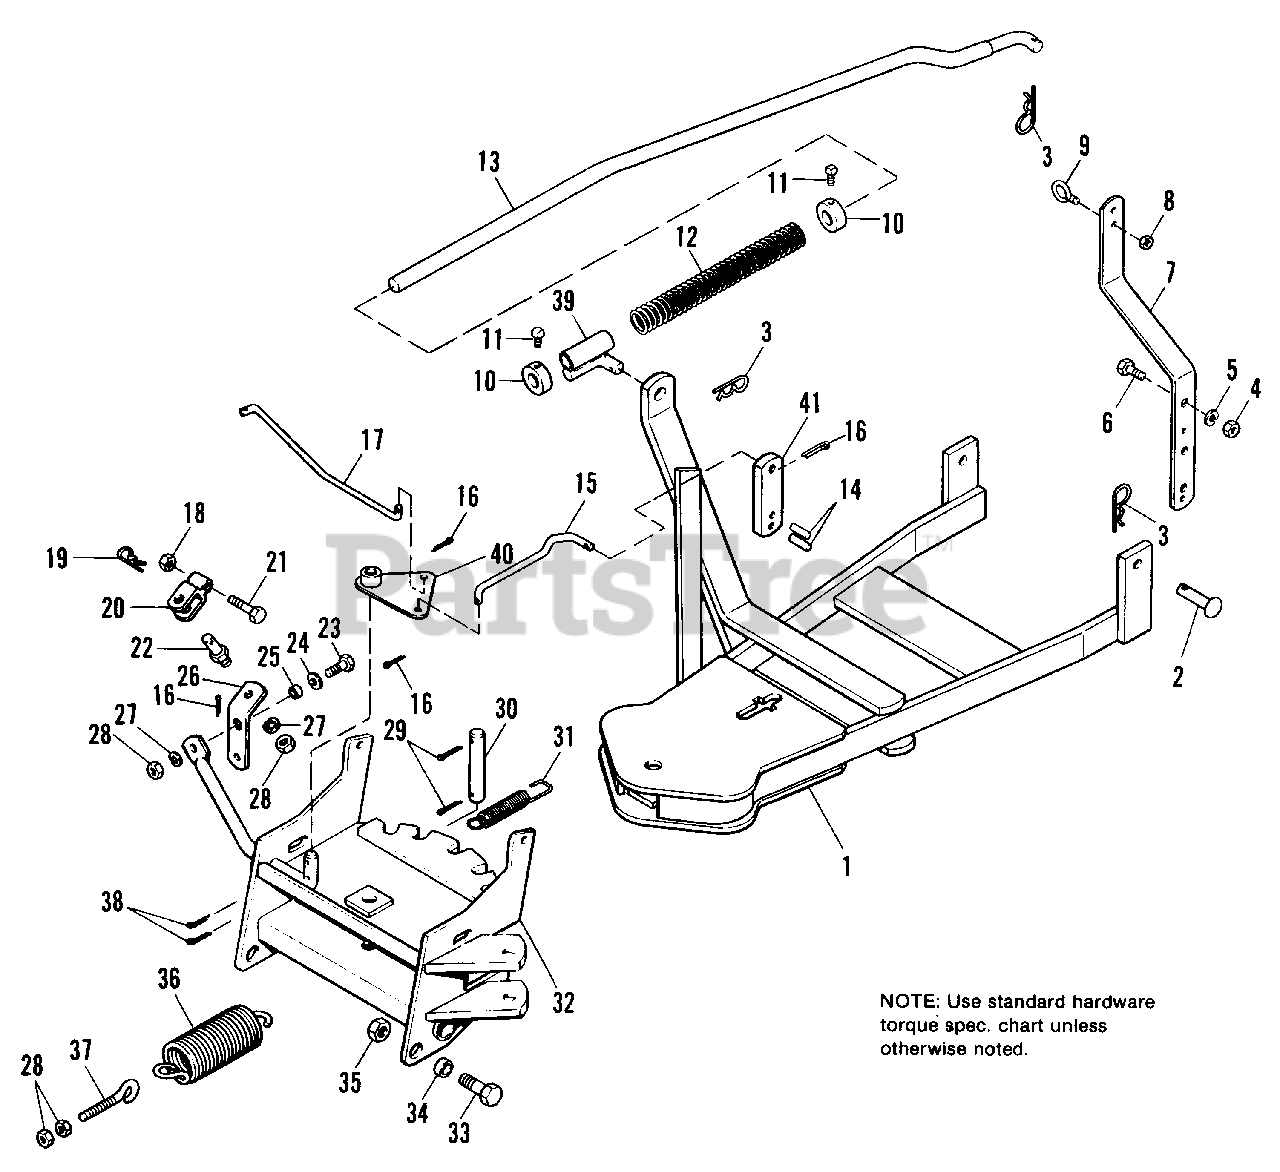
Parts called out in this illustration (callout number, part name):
1	BAR ASSY., Push
2	PIN
3	CLIP, Spring
4	NUT, Hex, Full, 3/8-16
5	LOCKWASHER, 3/8
6	CAPSCREW, Hex Hd., 3/8-16 x 7/8
7	BRACKET, Handle Support
8	LOCKNUT, Hex, 1/4-20
10	COLLAR, Set
11	SETSCREW, Sq. Hd., 5/16-18 x 1-1/2
14	PIN, Spring, 7/32 x 1
16	COTTER PIN, 3/32 x 3/4
18	LOCKNUT, Hex, 5/16-18
19	CLIP, Spring
21	CAPSCREW, Hex Hd., 5/16-18 x 1-1/2
22	STUD, Pivot
23	CAPSCREW, Hex Hd., 5/16-18 x 1
24	WASHER, Plain, 5/16
26	ARM, Pivot
27	LOCKWASHER, 5/16
28	NUT, Hex, Full, 5/16-18
29	COTTER PIN, 3/16 x 1-1/4
32	FRAME ASSY., Pivot
33	CAPSCREW, Hex Hd., 1/2-13 x 1
35	LOCKNUT, Hex, 1/2-12
36	SPRING, Tension
38	COTTER PIN, 1/8 x 1
39	GUIDE ASSY., Rod
40	PLATE ASSY., Pivot
